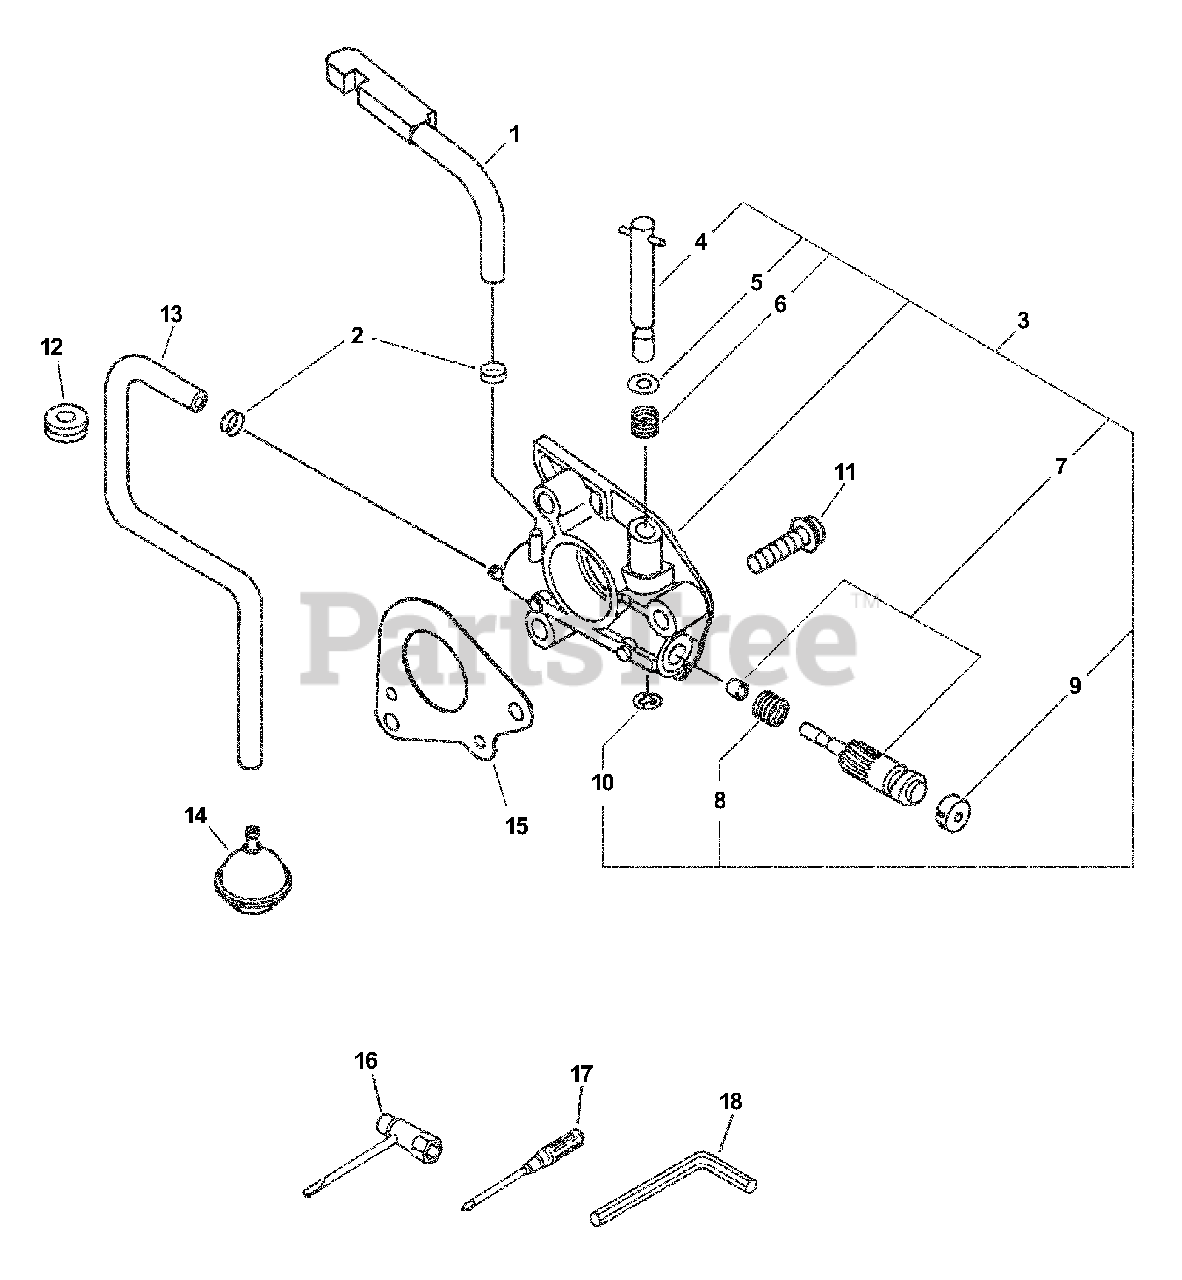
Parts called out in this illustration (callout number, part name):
1	PIPE - OIL
2	CLIP - 6.5
3	AUTO-OILER ASSY
4	NEEDLE, ADJUST
7	PLUNGER ASSY
8	SPRING, PLUNGER
9	CAP, OIL PUMP
10	RING, RETAINING
11	SCREW - 4X16
13	PIPE - OIL
14	FILTER, OIL
15	SEAL, DUST
16	T-WRENCH - 13X19mm
17	SCREWDRIVER
18	HEX KEY - 4mm
